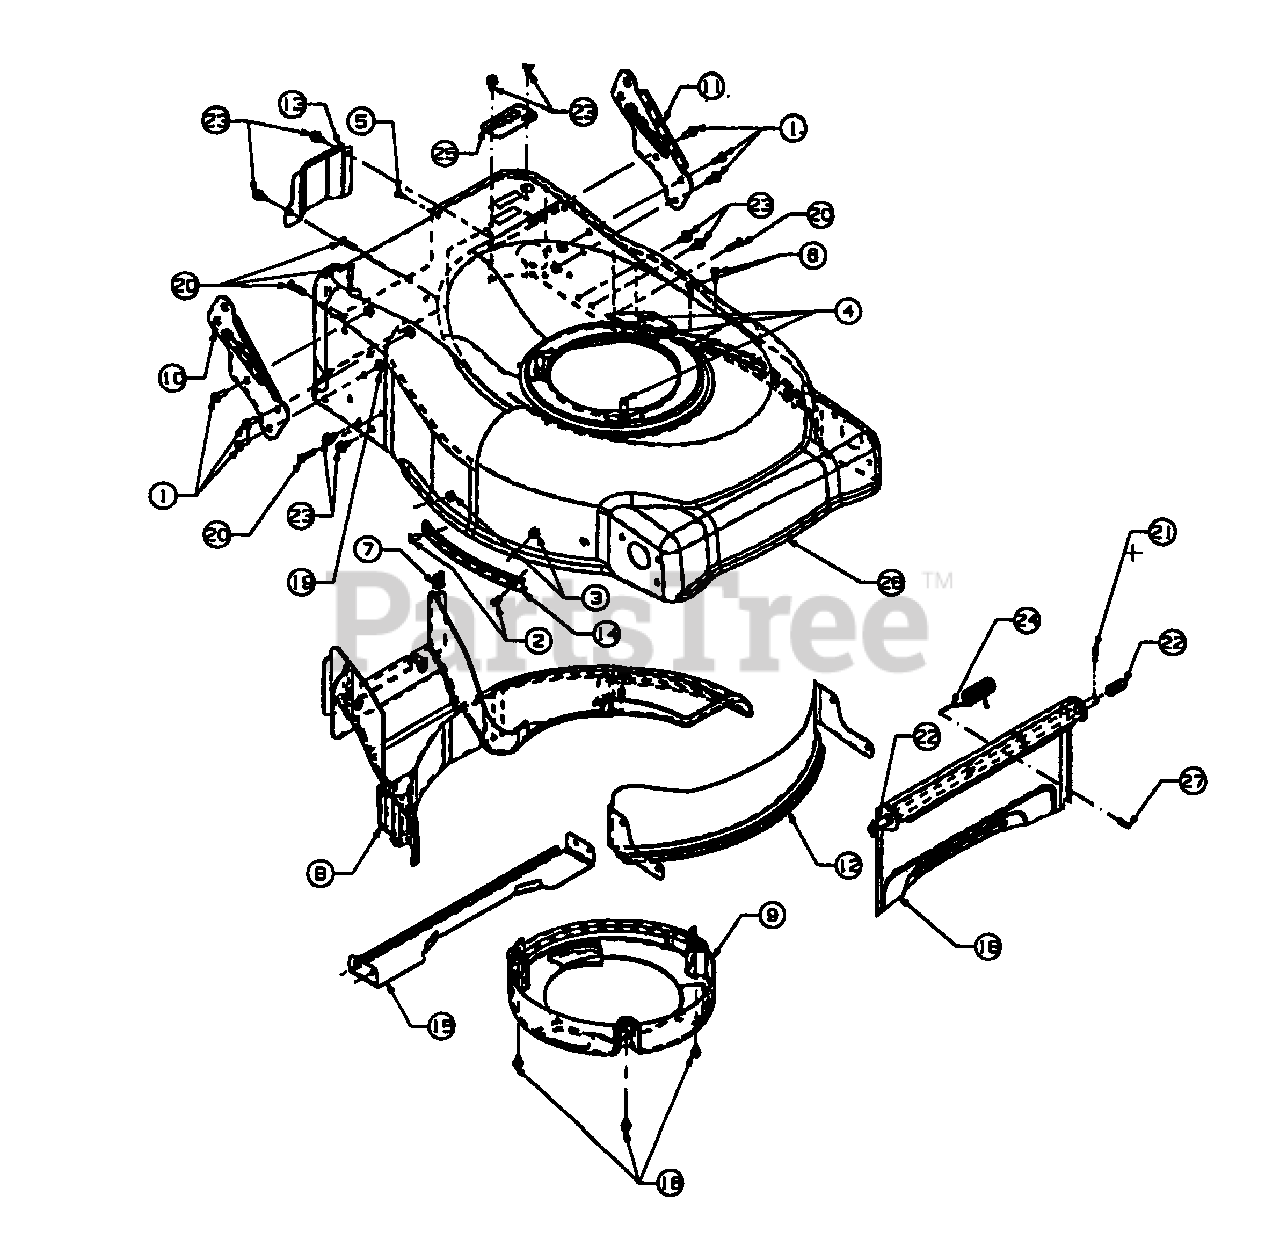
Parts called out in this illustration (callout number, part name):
1	HHCS 1/4-20 .820 GR5 STD
2	SCREW BUTTON HD. 1/4-20 X .5
3	NUT HX 1/4-20 GRC LOCK
4	SCR TTSEMS 3/8-16 1.250 HXLWS
5	SCR 8 #10-16 0.500 TRUSTRX1
6	SCR HL #12-16 0.750 TRUSTRX1
7	U-NUT #10-16
8	BFL RR 21" RD COMMERCIAL
9	CUR BELT 21 RD COMMERCIAL
10	BRKT HNDL RH, COMMERCIAL (BLACK)
11	BRKT HNDL LH, COMMERCIAL (BLACK)
12	BFL FRT COML, 10.81 R (YELLOW)
13	PLT CVR TRANS (YELLOW)
14	GUARD DECK SIDE FLANGE (YELLOW)
15	BRKT SUPT BAFFLE (BLACK)
16	SCR TT 1/4-20 .375 HX INDWSH
18	DOOR GRSBG 21" RB (BLACK)
19	NUT 1/4-20 HEXFLG LOCK OR F
20	SCR HL #12-16 1.000 TRUSTAXI
21	PIN COT INT .072 X 1.12 LG.
22	SPCR .75 X .50 X 1.02 LG.
23	SCR AB 1/4-14 0.825 HX INDWSH
24	SPR TORSN LH 0.120 X 15C
25	BRKT SHFT SELCT
26	DECK RD 21" COMMERCIAL (YELLOW)
27	VINYL CAP
